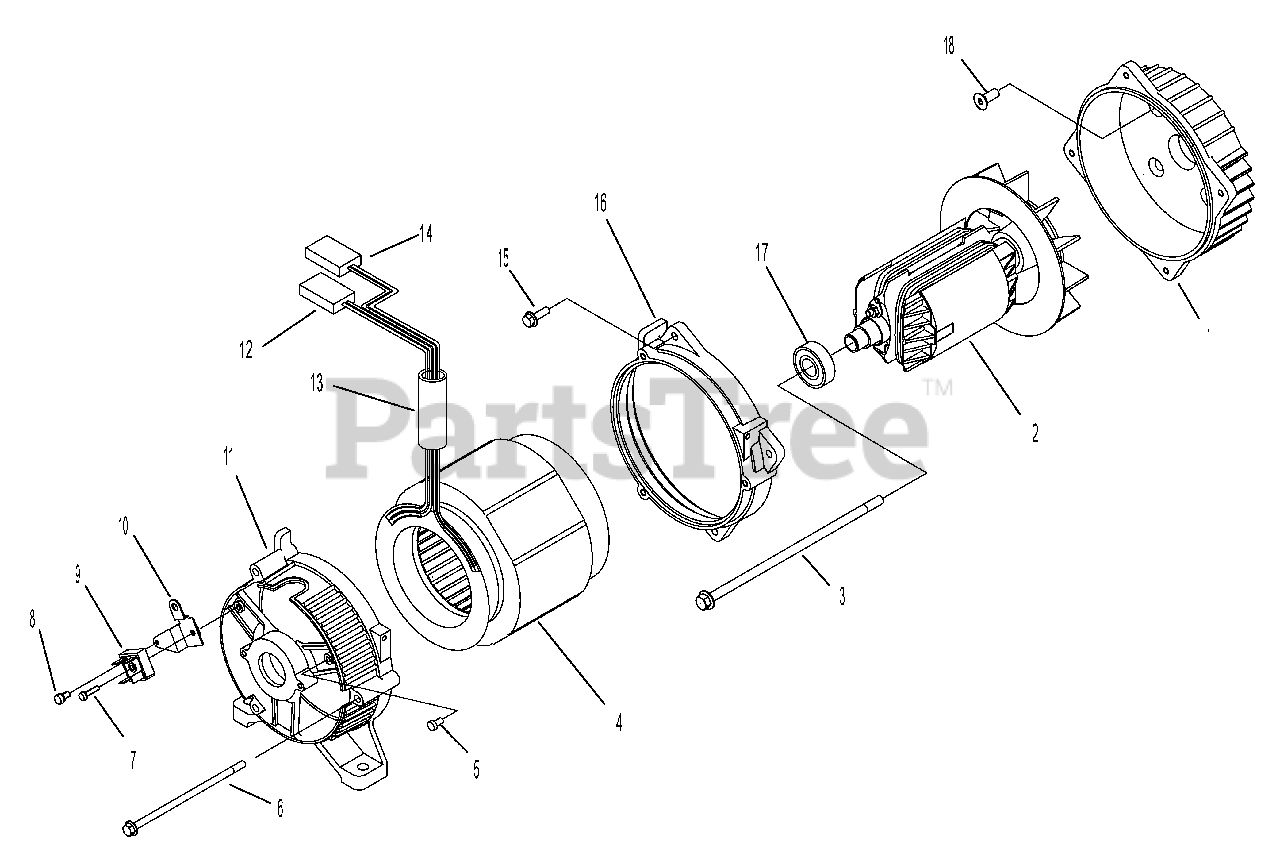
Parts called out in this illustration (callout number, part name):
1	Adptr, Eng
3	Bolt, Rotor
5	Screw, M5 x 7
10	Bracket, Rectifier
11	RBC
16	Adptr, Mntng, Alt
